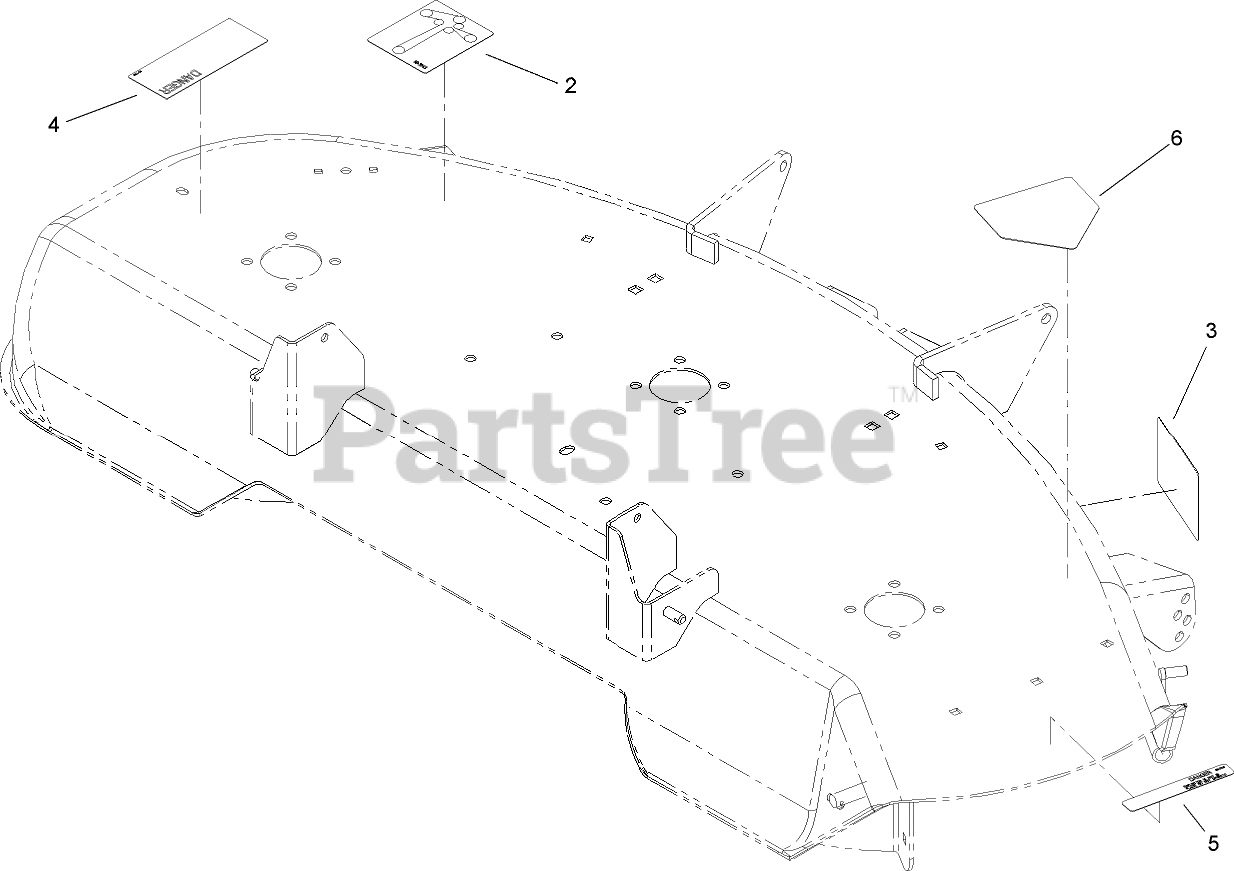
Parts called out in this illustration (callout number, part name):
2	DECAL-ROUTING, BELT
3	DECAL-WHEEL, GAGE
4	DECAL-DANGER
5	DECAL-CAUTION
6	DECAL-DANGER
